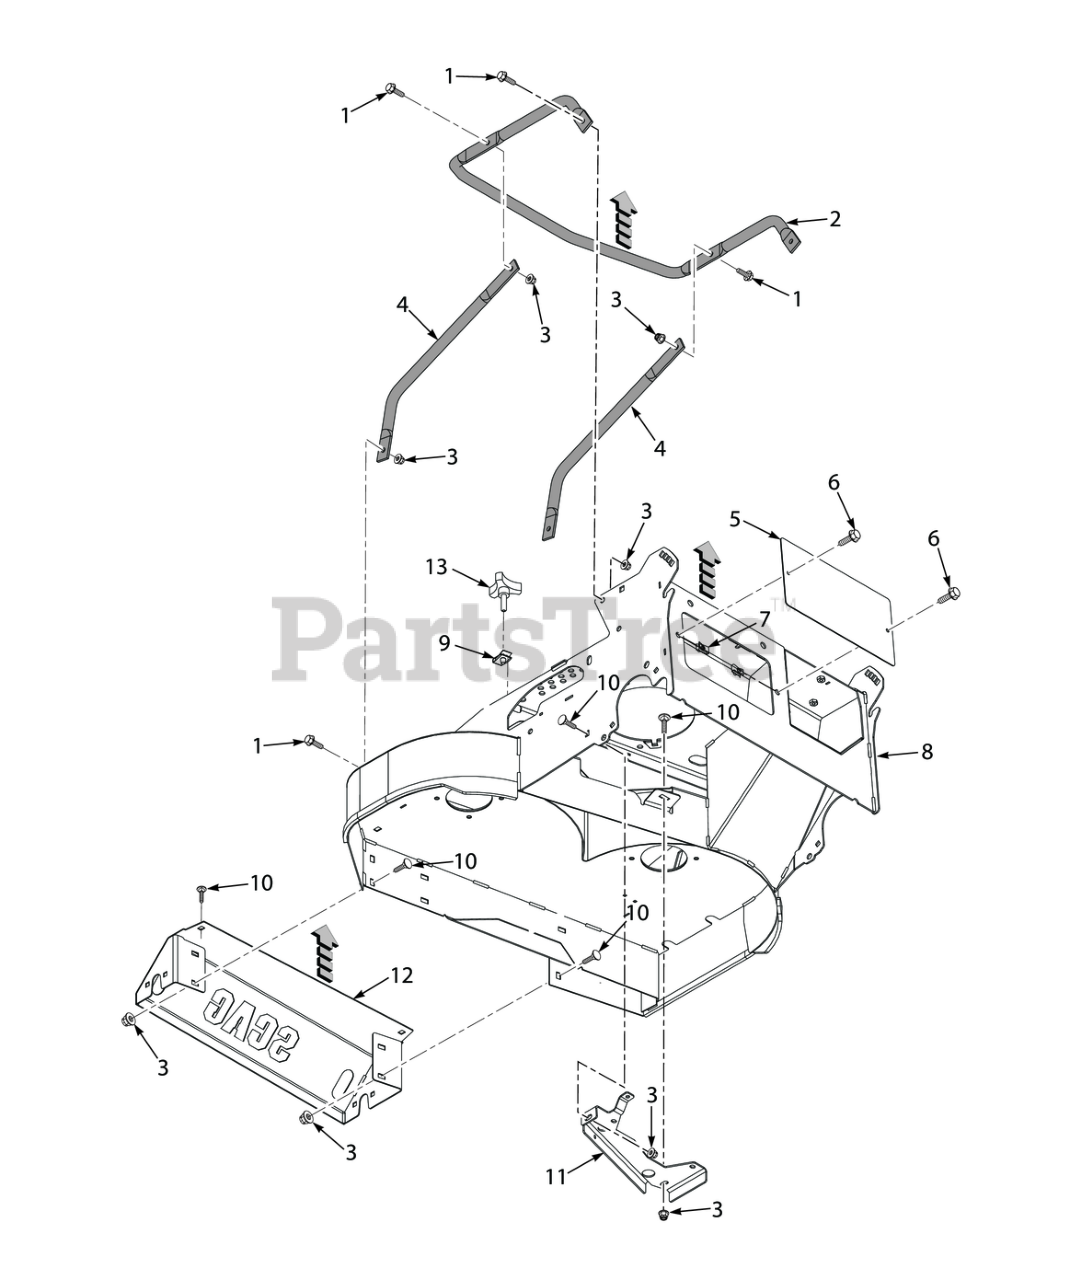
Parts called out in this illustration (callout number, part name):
1	Capscrew, 5/16-18 x .75 Serrated Flange Hex Head
2	Guard, Engine
3	Nut, Flange Head Elastic Stop 5/16-18
4	Guard Bracket, Side
5	Cover, Transmission Access
6	CAP SCREW, 1/4-20 X 1/2" SERRATED FLANGE HEX
7	Bolt, Hex Head 3/8-16 x 1"
8	Frame w/Decals
9	U-Nut, 3/8-16 (short)
10	Bolt, 5/16-18 x .75 RHSN Carriage
11	Mounting Bracket, Transmission
12	Weldment, Front Axle Support
13	Knob, w/stud 3/8-16 x 1-1/4"
